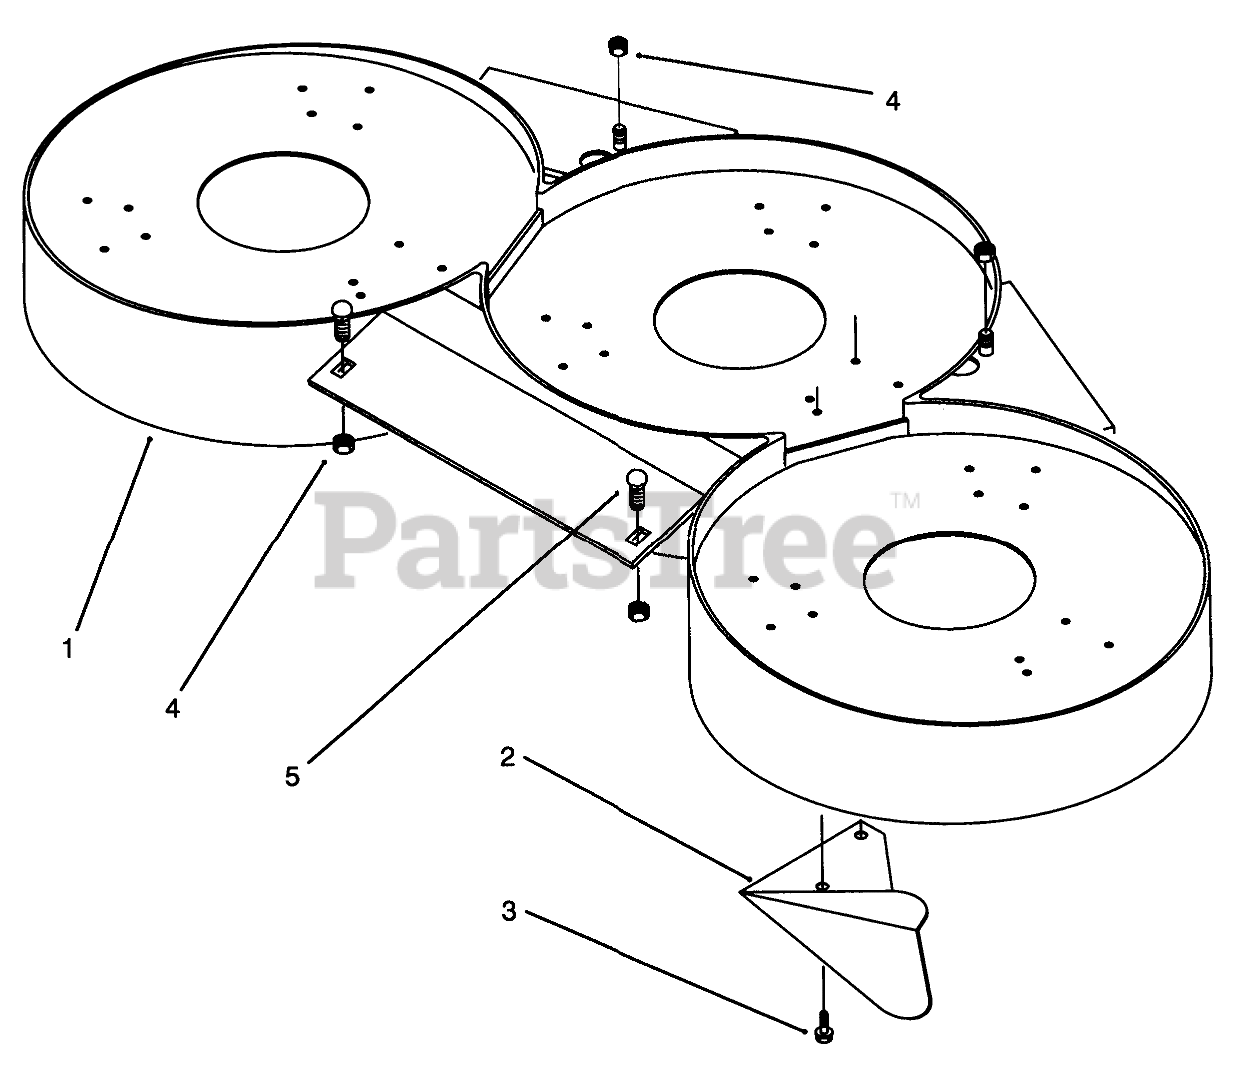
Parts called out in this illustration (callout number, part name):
1	Baffle
2	Kicker
3	SCREW-HWH
4	NUT-LOCK, NI
5	BOLT-CARR
